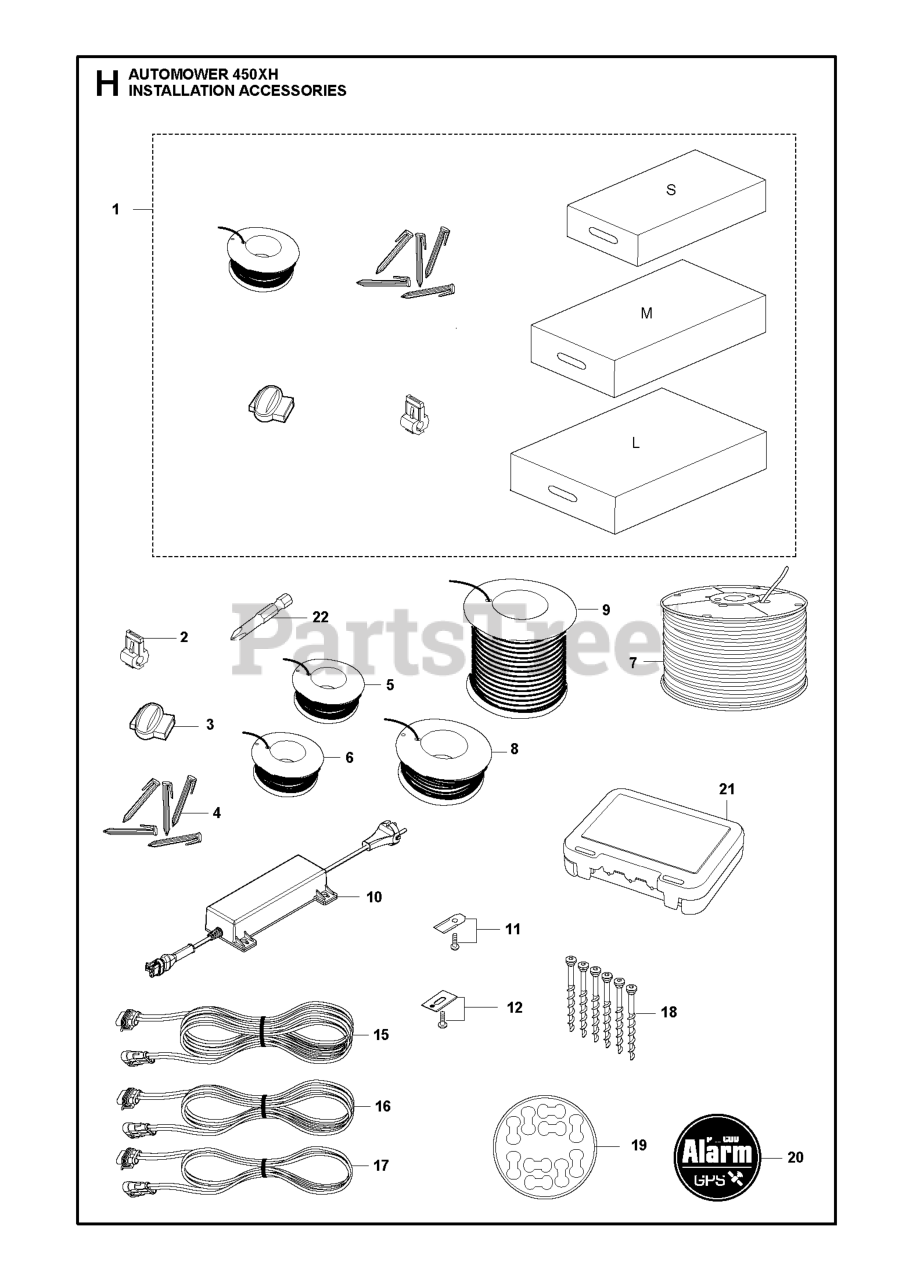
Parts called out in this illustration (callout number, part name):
1	SMALL AUTOMOWER INSTALL KIT
1	LARGE AUTOMOWER INSTALL KIT
1	MED AUTOMOWER INSTALL KIT
2	CONNECTOR 5 PCS, BLISTER
2	CONNECTOR 100 PCS
2	BRAKER
3	COUPLER SPLICER, 100 PCS
3	COUPLER SPLICER, 5 PCS,
3	SPLICE KIT
4	STAPLE 100 PCS, BLISTER
4	STAPLE 100 PCS
5	WIRE 150M, BLISTER
5	WIRE 50M STANDARD Ø2.7MM,BLIST
5	WIRE BOUNDARY 150M
6	WIRE 250M
8	WIRE 500M
9	WIRE (800M)
10	Power Unit
11	HUS BLADE SET 9 PCS
11	HUS BLADE SET 300 PCS
11	HUS BLADE SET 45 PCS
15	CABLE LOW VOLTAGE CABLE P2 5-7
16	CABLE LOW VOLTAGE CABLE P2 5-7
17	CABLE LOW VOLTAGE CABLE P2 5-7
18	SCREW 3 PCS, BLISTER PACK
18	SCREW KIT CS
19	STICKER CABLE MARKERS KIT 10PC
20	Decals
21	CONNECTOR PROTECTION BOX
22	WRENCH BITS CHANGING ROBOTIC B
